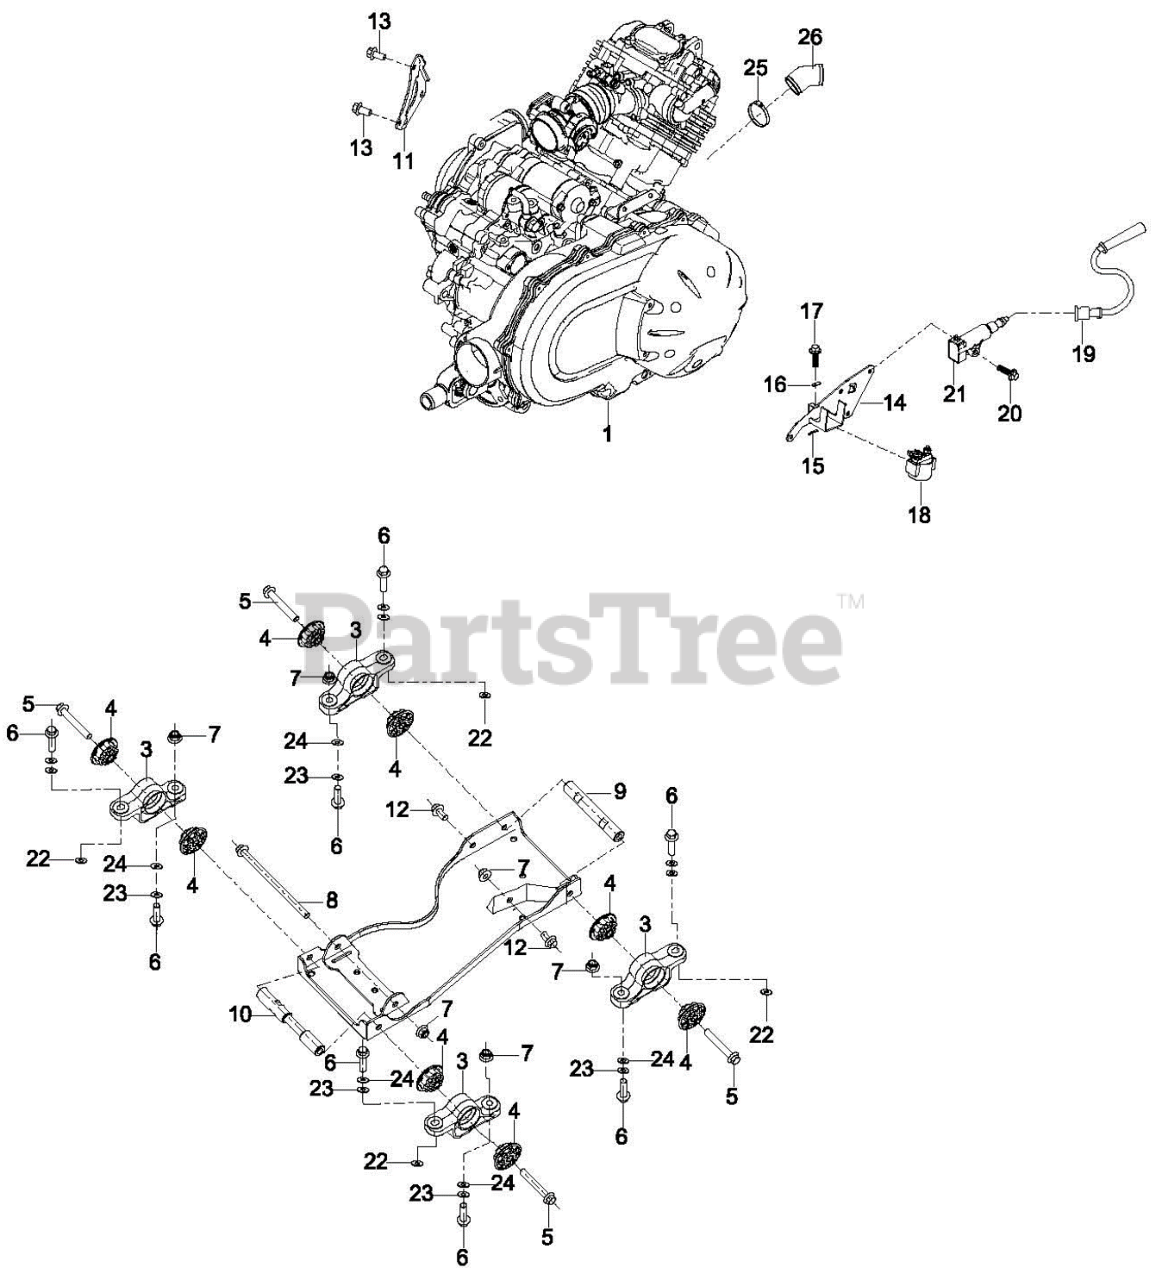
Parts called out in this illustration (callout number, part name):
1	COMPLETE ENGINE 750cc
1	COMPLETE ENGINE 550cc
2	ENGINE CRADLE
3	ENGINE MOUNT
4	RUBBER ENGINE MOUNT
5	HEXAGON FLANGE BOLTM10X1.25X70
6	HEX BOLT-FLG HEAD 10x1.25x35
7	LOCK NUT M10X1.25
8	HEX HEAD BOLT M10X1.25-175
9	SPACER ROD (REAR)
10	SPACER ROD (FRONT)
11	ENGINE MOUNT BRACKET
12	HEX FLANGE BOLT M10X1.25X20
13	CROSS PLATE HEAD SCREW M8X16
14	IGNITION COIL MOUNT
15	FOAM CUSHION
16	STARTER RELAY LATCH
17	CROSS PLATE HEAD SCREW M6X12
18	STARTER RELAY
19	IGNITION CABLE (750cc Engine)
19	IGNITION CABLE (550cc Engine)
20	HEXAGON FLANGE BOLT M6X40
21	IGNITION COIL
22	WASHER - FLAT 10X28X2
23	SPRING WASHER
25	HOSE CLAMP ASSEMBLY
26	FAN OUTLET DUCT
